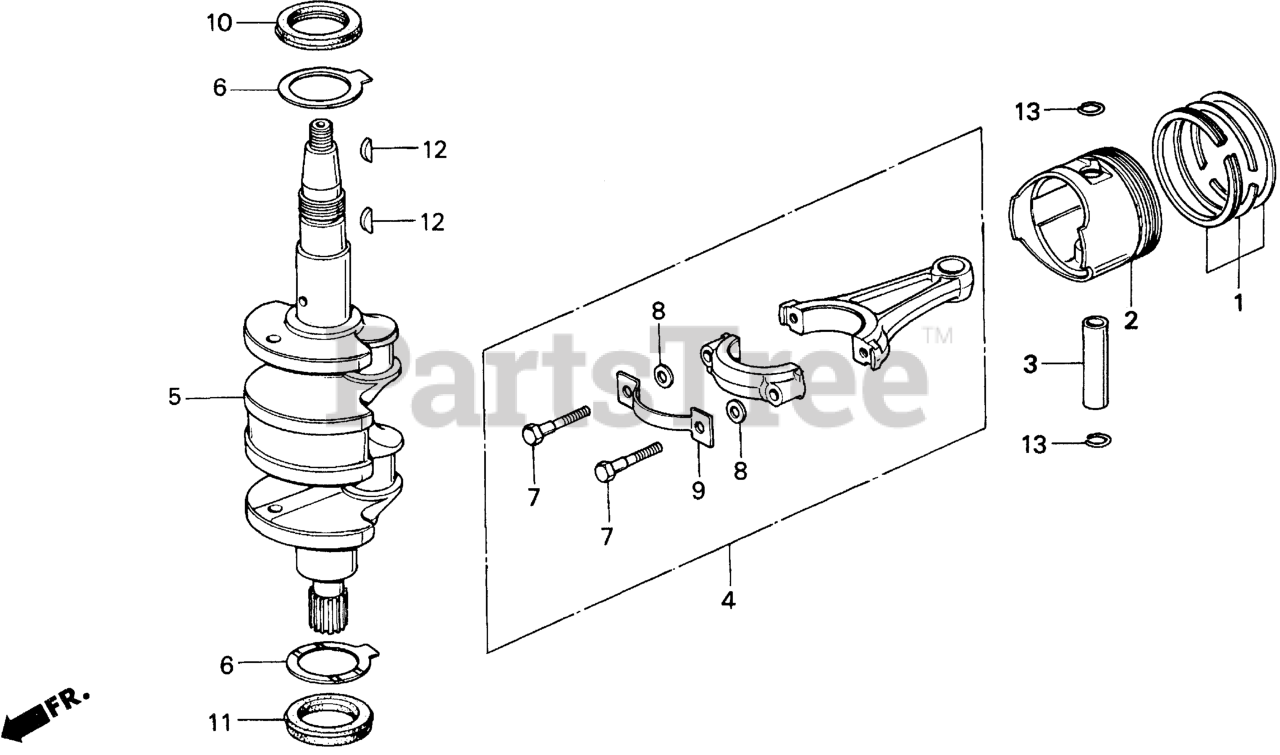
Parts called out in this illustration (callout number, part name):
1	RING SET, PISTON (2SET) (STD)
3	PIN, PISTON
4	ROD ASSY., CONNECTING
5	CRANKSHAFT, R.
6	BEARING, CRANKSHAFT THRUST
7	BOLT, CONNECTING ROD
8	WASHER (6MM)
9	WASHER, LOCK
10	OIL SEAL A (30X42X7)
11	OIL SEAL B (30X42X7)
12	KEY, WOODRUFF (16X15)
13	CLIP, PISTON PIN (14MM)
